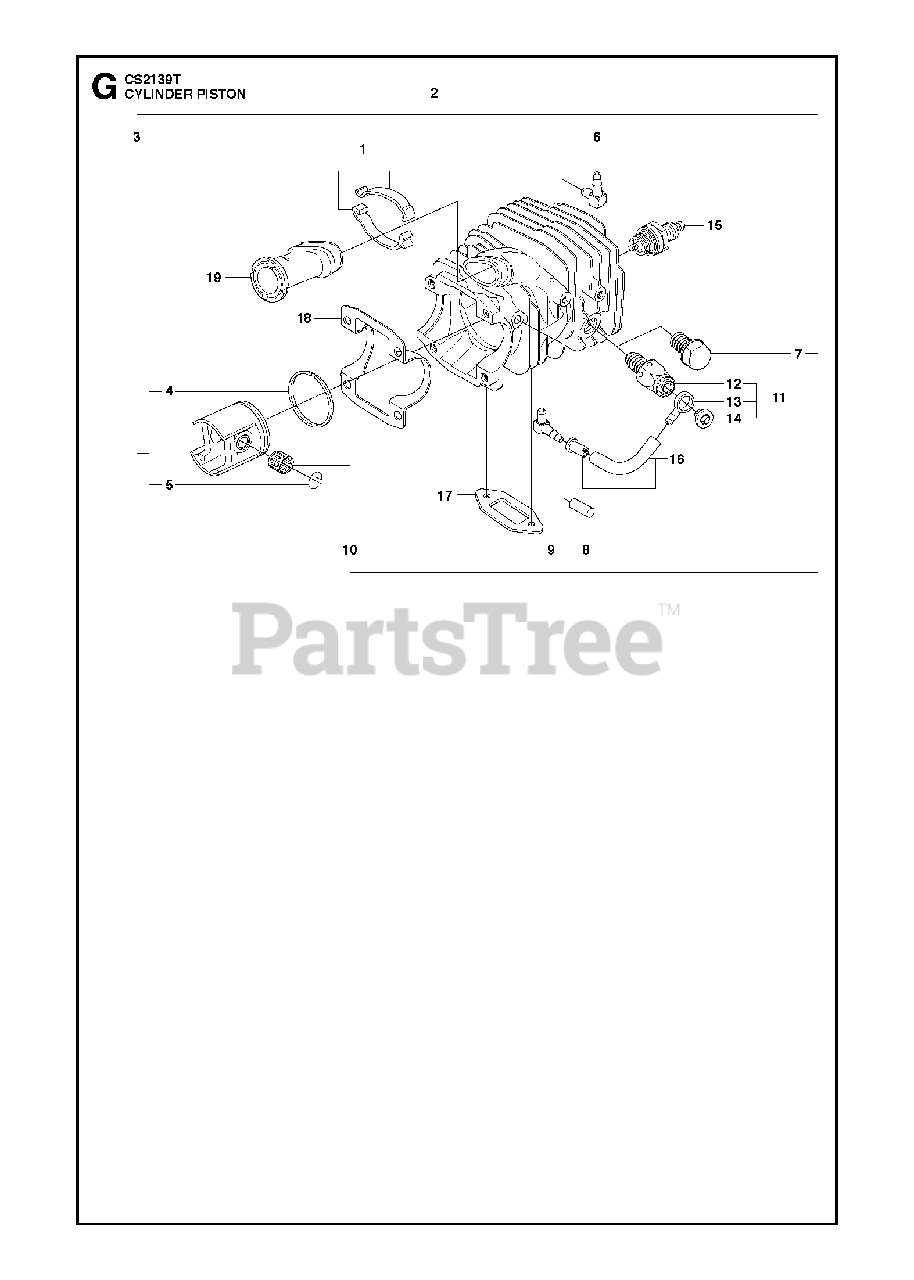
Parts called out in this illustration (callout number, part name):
3	PISTON
4	RING
5	LOCKING RING
6	NIPPLE
7	CYLINDER PLUG
8	PROTECTIVE CAP
9	NIPPLE
10	SUPPORT BUSHING
11	VALVE DECOMPR
12	DECOMPRESSION VALVE
13	NIPPLE
14	SCREW
15	SPARK PLUG RCJ7Y
16	HOSE ASSY
